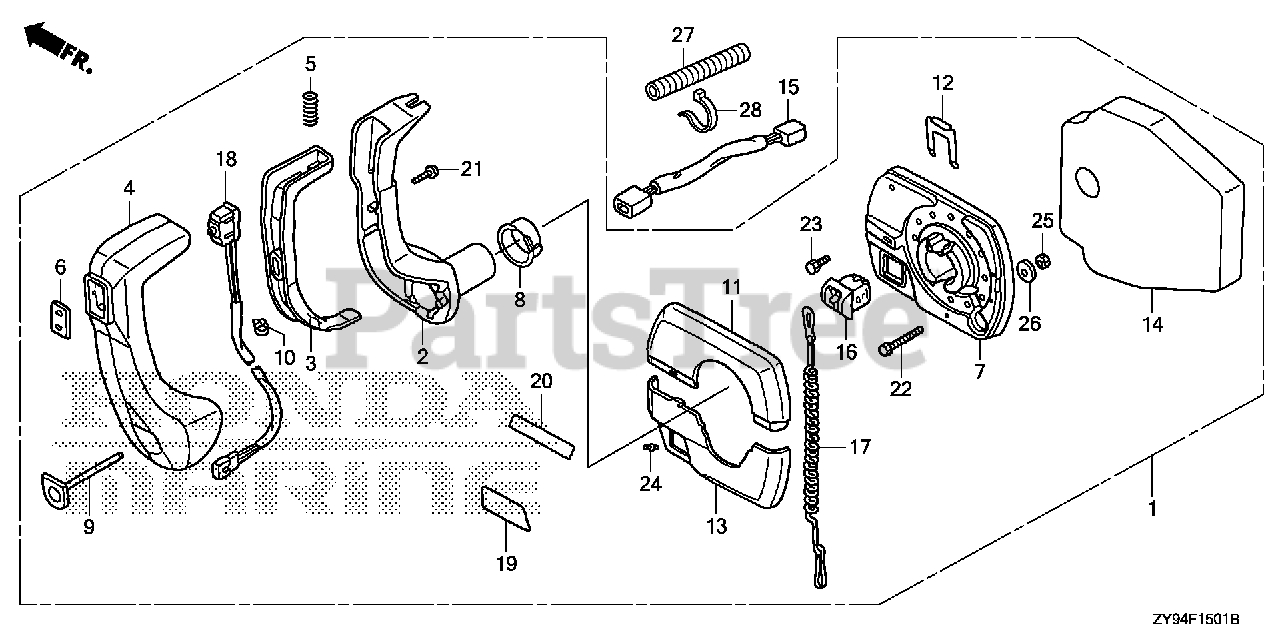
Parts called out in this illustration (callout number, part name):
1	BOX ASSY., REMOTE CONTROL (PANEL MOUNT) (NA USE ALT:06240-ZW7-U00)
2	HANDLE, REMOTE CONTROL
3	LEVER, HANDLE LOCK
4	GRIP, REMOTE CONTROL HANDLE
5	SPRING, REMOTE CONTROL HANDLE
6	COVER, GRIP
7	HOUSING ASSY., REMOTE CONTROL BOX (A)
8	BUSHING Use up to Frame SN 4000953.
9	BUTTON, THROTTLE
10	BAND B, CABLE Use up to Frame SN 4000953.
11	HOUSING ASSY., REMOTE CONTROL BOX (B)
12	RETAINER
13	HOUSING, REMOTE CONTROL BOX (C)
14	HOUSING ASSY. (INNER) (PANEL MOUNT)
15	HARNESS ASSY., POWER TRIM-TILT Use from Frame SN 4000954.
16	SWITCH ASSY., EMERGENCY STOP
17	WIRE, EMERGENCY
18	SWITCH ASSY., POWER TRIM-TILT (A) Use up to Frame SN 4000953.
19	MARK, REMOTE CONTROL (A)(PANEL)
20	MARK, REMOTE CONTROL (B)(FOR STARBOARD)
20	MARK, REMOTE CONTROL (C)(FOR PORT)
21	SCREW A (NOT AVAILABLE)
22	SCREW B
23	SCREW C
24	SCREW SET (1/4-20X16") Use up to Frame SN 4000953.
25	NUT (1/4X20)
26	WASHER
